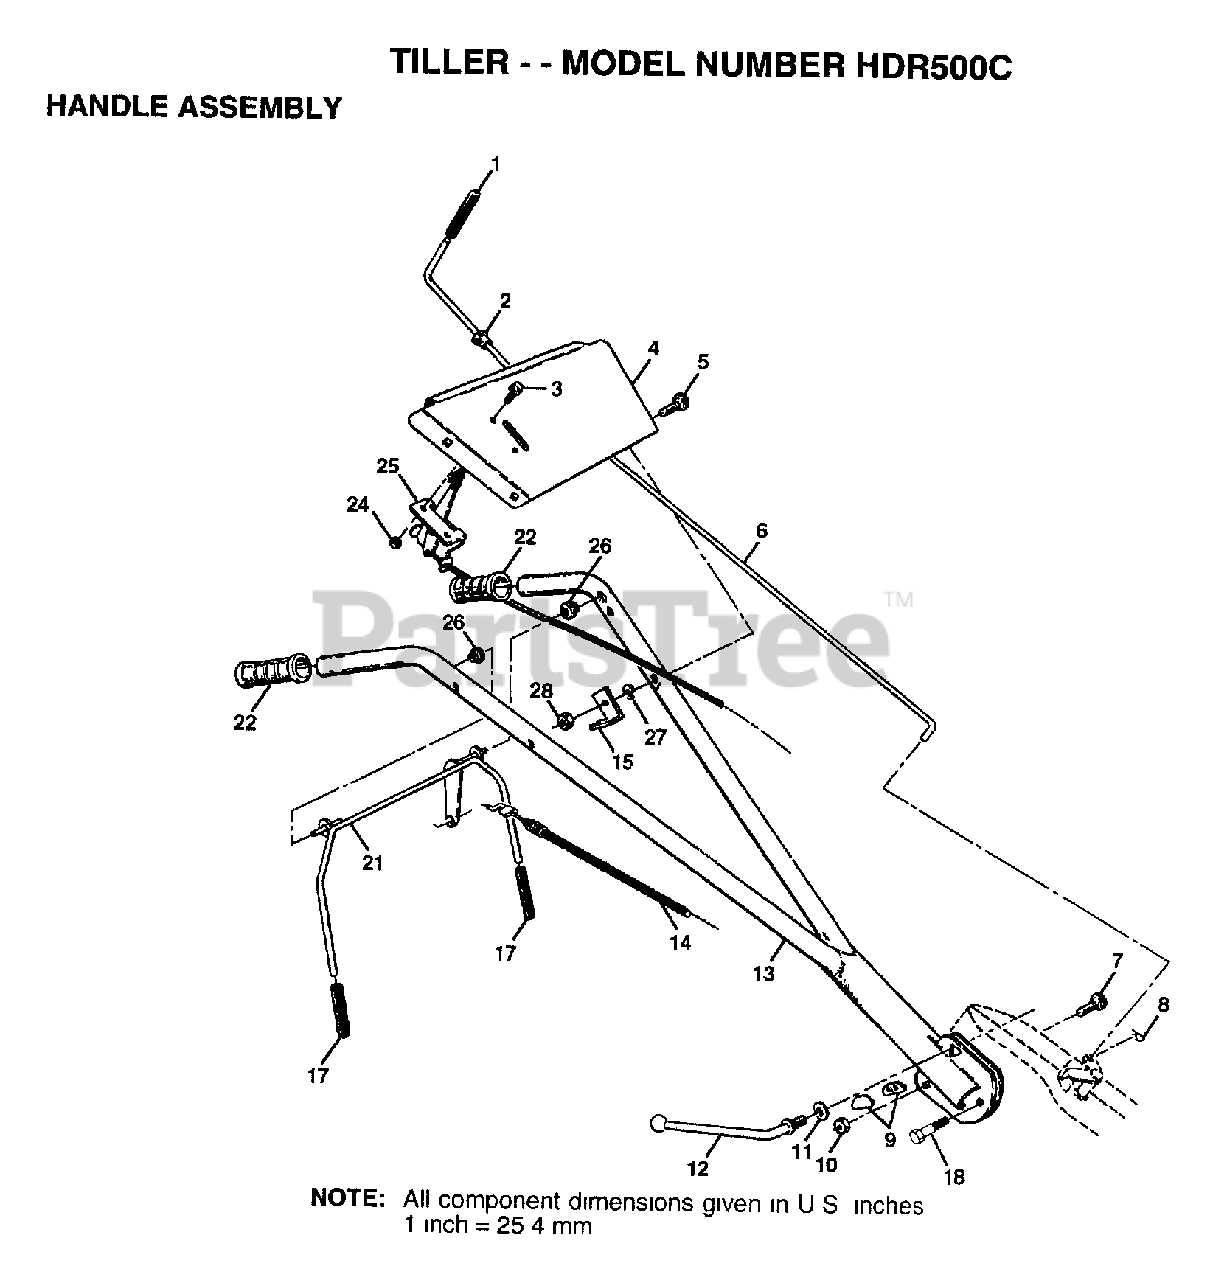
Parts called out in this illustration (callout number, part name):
1	GRIP TI
2	BUSHING
3	SCREW.PNHD.10-24
4	BRACKET.HDLE.TILL
5	BOLT CARRIAGE CRT
6	ROD SHIFT CRT
7	BOLT D
8	RETAINER M
9	LOCK CRT
10	LOCKNUT
11	WASHER CRT
12	LEVER LOCK CRT
14	CABLE.CLUTCH.Z-BE
15	BRACKET.CLUTCH.CA
17	GRIP BAR CRT
18	BOLT PIVOT
21	BAR.ASM.CNTRL.VPL
22	"GRIP,HANDLE"
25	"CONT,THROTTLE"
26	GROMMET.HANDLE.V-
27	LOCKWASHER
28	NUT
